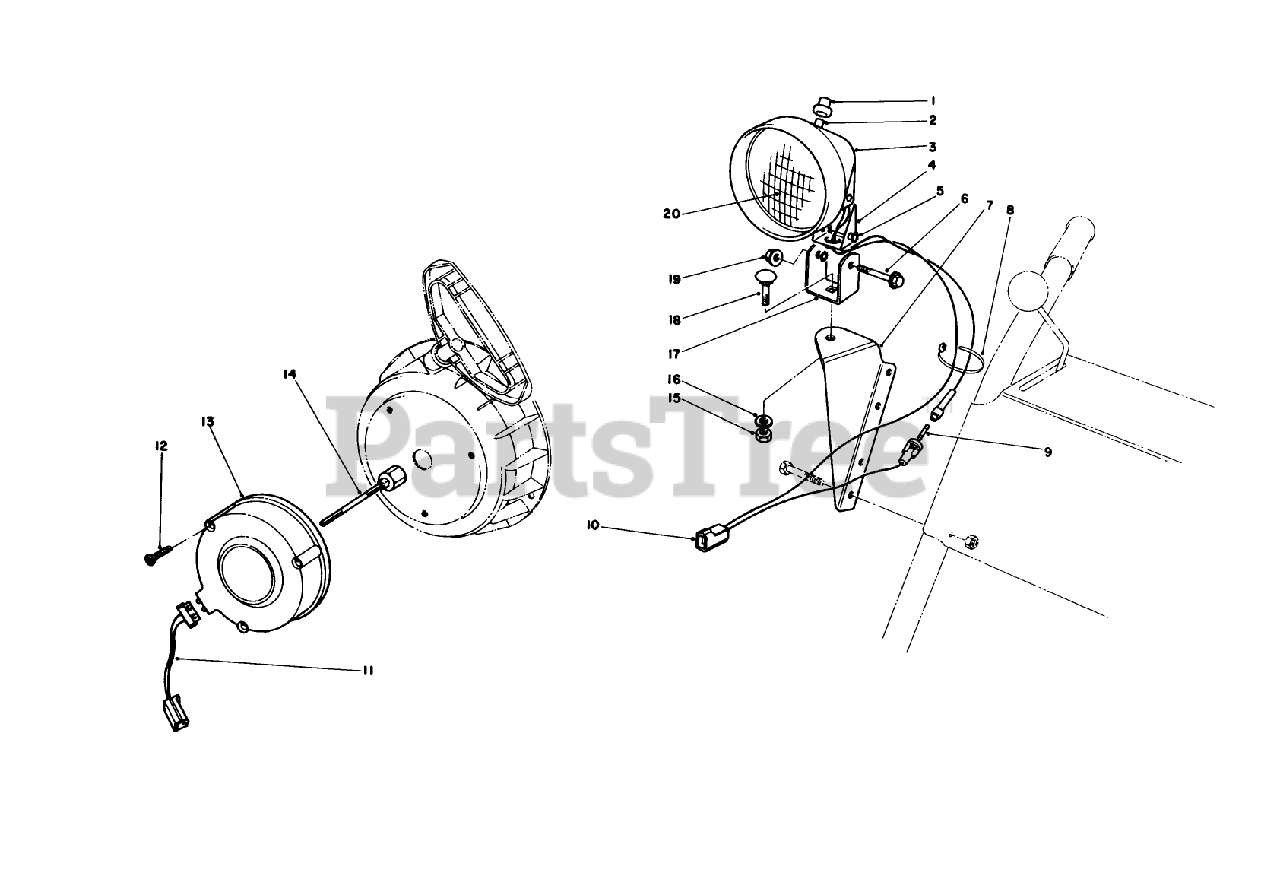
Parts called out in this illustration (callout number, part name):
1	BOOT-SWITCH
2	SWITCH ASM
3	Bucket-Headlamp
4	TO BE DISCONTINED-NOT NEEDED ON PRODUCT
5	WASHER-LOCK
6	SCREW-HH
7	LAMP MOUNT B
8	TIE-CABLE
9	Fuse-7-1 /2 Amp.
10	WIRE ASM
11	Connector-Wire
12	SELF TAP SCREW
13	Alternator
14	Shaft-Alternator, 3 Inch
15	NUT-HEX
16	WASHER-LOCK
17	BRACKET
18	BOLT-CARR
19	NUT-HF
20	BEAM-SEALED
